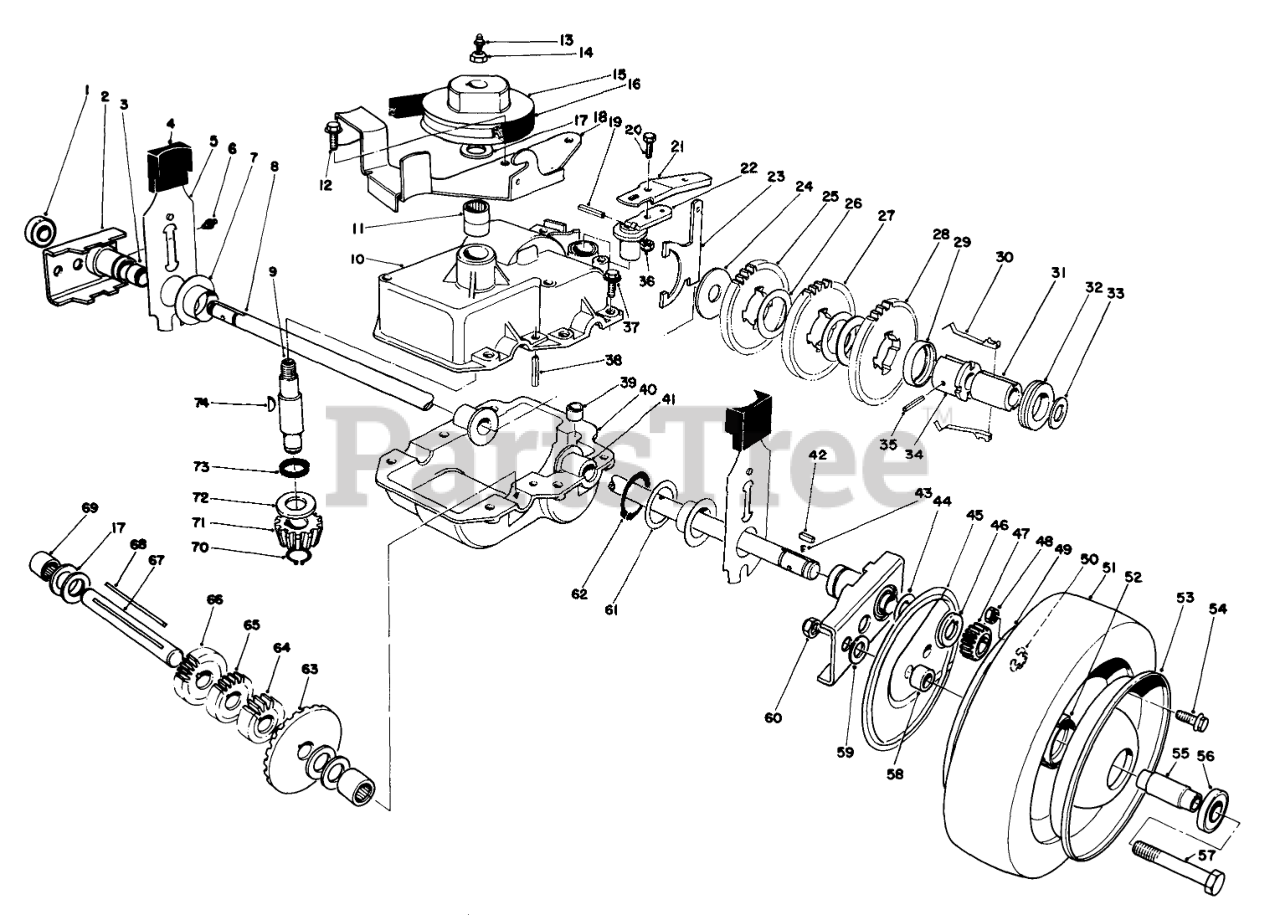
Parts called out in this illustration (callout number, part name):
1	BEARING-WHEEL
2	Pivot Arm Assembly (Incl. Ref. #1, 3 & 6)
3	BUSHING
4	KNOB-ARM
5	Spring Arm Assembly-Rear
6	FITTING-GREASE
7	CAP-END
8	Shaft-Output
9	Shaft Input
10	Upper Case Assembly (Incl. Ref. #11 & 73)
11	BEARING-NEEDLE
12	SCREW
13	FITTING-GREASE
14	NUT-HEX
15	PULLEY
16	V-BELT
17	WASHER-THRUST
18	Belt Guide Bracket
19	PIN-COIL
21	SHIFT LEVER COVER
22	LEVER-SHIFT
23	Shift Yoke
24	WASHER
25	GEAR-38T
26	WASHER
27	GEAR-42T
29	RETAINER-KEY
30	KEY-SHIFT
31	SLEEVE
32	COLLAR-SHIFT
33	WASHER-PLAIN
34	SLEEVE-GEAR
35	PIN-GROOVE
36	NUT-LOCK, NI
37	SCREW-HWHTF
38	ROLL PIN 3/16 X 1 IN
39	BUSHING-YOKE
40	Case-Lower
41	BUSHING
42	KEY RECTANGULAR
43	SPRING-COMPRESSION
44	WASHER-THRUST, OUTER
45	WHEEL COVER
46	WASHER-THRUST, OUTER
47	GEAR-PINION
48	NUT-LOCK, NI
49	Wheel-Half
50	RING-RETAINING
52	HUB-BEARING
53	Wheel-Half
54	SCREW-HHF
55	SPACER-BEARING
56	BEARING-WHEEL
57	SCREW-HH
58	SPACER-WHEEL
59	WASHER
60	NUT-LOCK, CONE
61	WASHER
62	RING-RETAINING
63	BEVEL GEAR
64	GEAR-12T
65	GEAR-14T
66	GEAR-18T
67	SHAFT-INTERMEDIATE
69	BEARING-NEEDLE, CLOSED
70	RING-RETAINING
71	PINION-BEVEL
72	WASHER-THRUST
74	KEY-WOODRUFF
